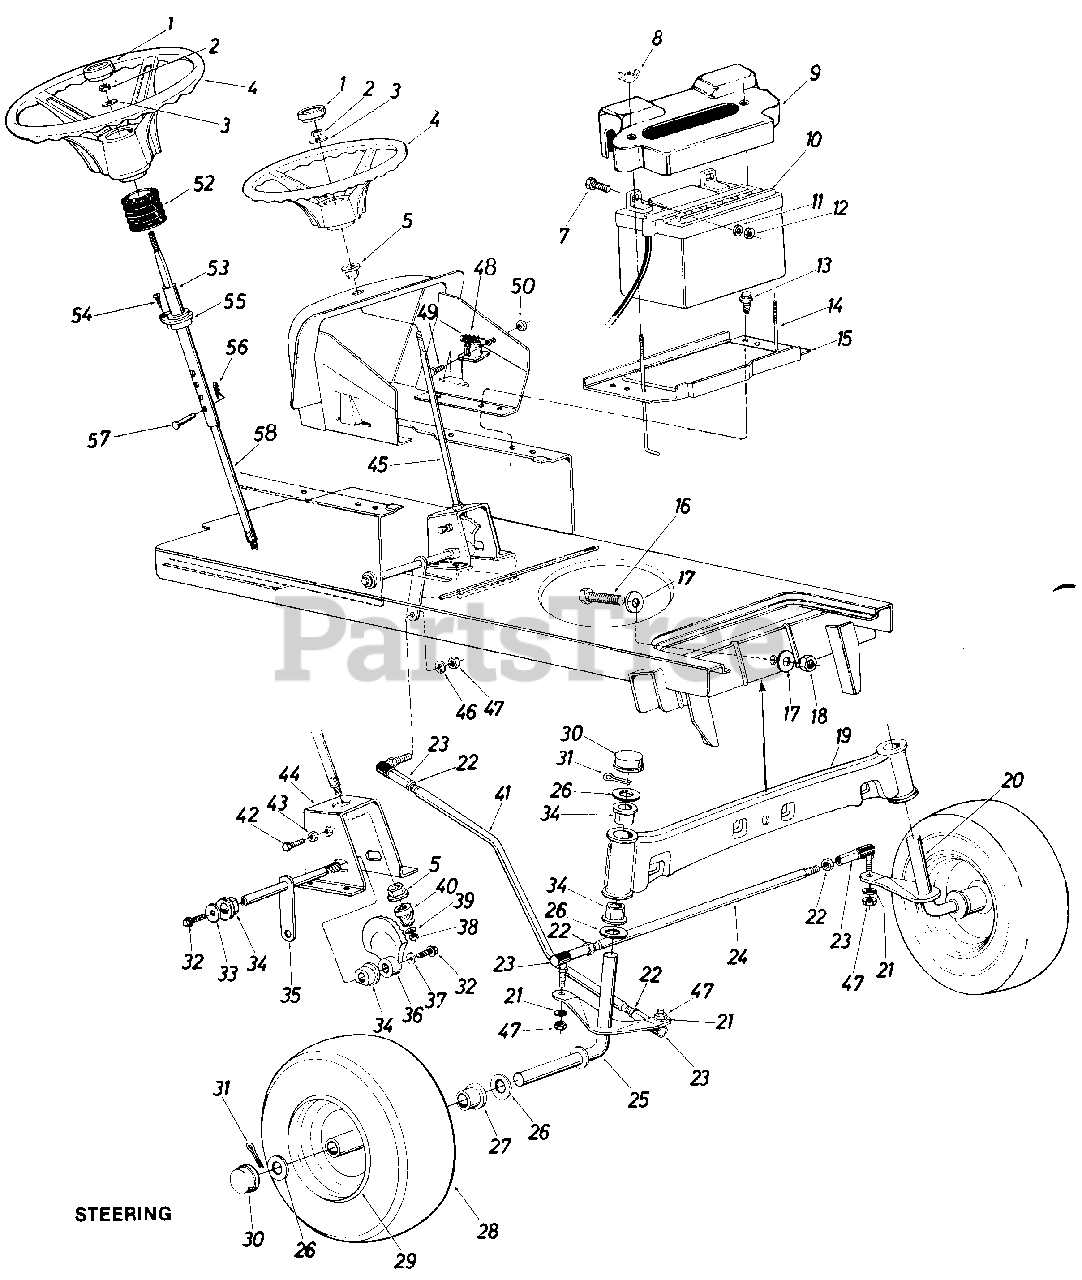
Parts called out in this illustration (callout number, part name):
1	Steering Wheel Cap
2	Hex Cent. L-Nut 5/16-18 Thd.
3	Bell-Wash. 5/16" I.D. x .87" O.D. x .060
4	Steering Wheel
5	Plastic Hex Bearing 5/8" I.D.
7	Hex Scr. 1/4-20 x .62" Lg.
8	Wing Nut Plastic 1/4-20 Thd.
9	Battery Cover
10	12-V Battery
11	L-Wash 1/4" Scr.*
12	Hex Nut 1/4-20 Thd.*
13	Hex Thd. Rolling Scr. 1/4-20 x.50" Lg.
14	Battery Hold Down Rod
15	Battery Plate
16	Hex Scr. 5/8-18 x 2.50" Lg.
17	Flat Wash. .66" I.D. x 2.25" O.D. x .17
18	Hex Cent. L-Nut 5/8-18 Thd.
19	Front Pivot Bar Ass'y.
20	Front Axle Ass'y.-L.H.
21	L-Wash. 3/8" Scr.*
22	Hex Jam Nut 3/8-24 Thd.
23	Ball Joint Ass'y.
24	Tie Rod
25	Front Axle Ass'y.-R.H.
26	Fl-Wash. .780 I.D. x 1.59 O.D.
27	Flange Bearing
28	Front Wheel Ass'y. Comp.
29	Front Wheel Rim Only
30	Dust Cover
31	Cotter Pin 5/32" Dia. x 1.00" Lg. *
32	Hex Scr. 3/8-24 x .75" Lg. Grade 5
33	Fl-Wash. 3/8 I.D. x 1.25 O.D. x .090
34	Flange Double "D" Brg. .753 I.D.
35	Steering Arm Shaft Ass'y.
36	Side Gear-Steering
37	Bell-Wash. 3/8" I.D.
38	Hex Cent. L-Nut 5/16-24 Thd.
39	Fl-Wash. 5/16" I.D. x .62 O.D. x .059
40	Pinion Gear-Steering
41	Drag Link
42	Hex Nylon Scr. 3/8-16 x 1.25" Lg.
43	Hex Nut 3/8-16 Thd.*
44	Steering Gear Sup. Ass'y.
45	Steering Shaft
46	L-Wash. 3/8" Scr.*
47	Hex Nut 3/8-24 Thd.*
48	Solenoid
49	Hex Bolt 1/4-20 x .50" Lg.*
50	Hex Sems Nut 1/4-20 Thd.
52	Steering Bellow
53	Upper Steering Shaft
54	Oval Hd. Cr.-Sunk Scr. #10 x 5/8" Lg.
55	Fl-Bearing .89" I.D. x 1.36" O.D.
56	Hairpin Cotter
57	Clevis Pin
58	Lower Steering Shaft
